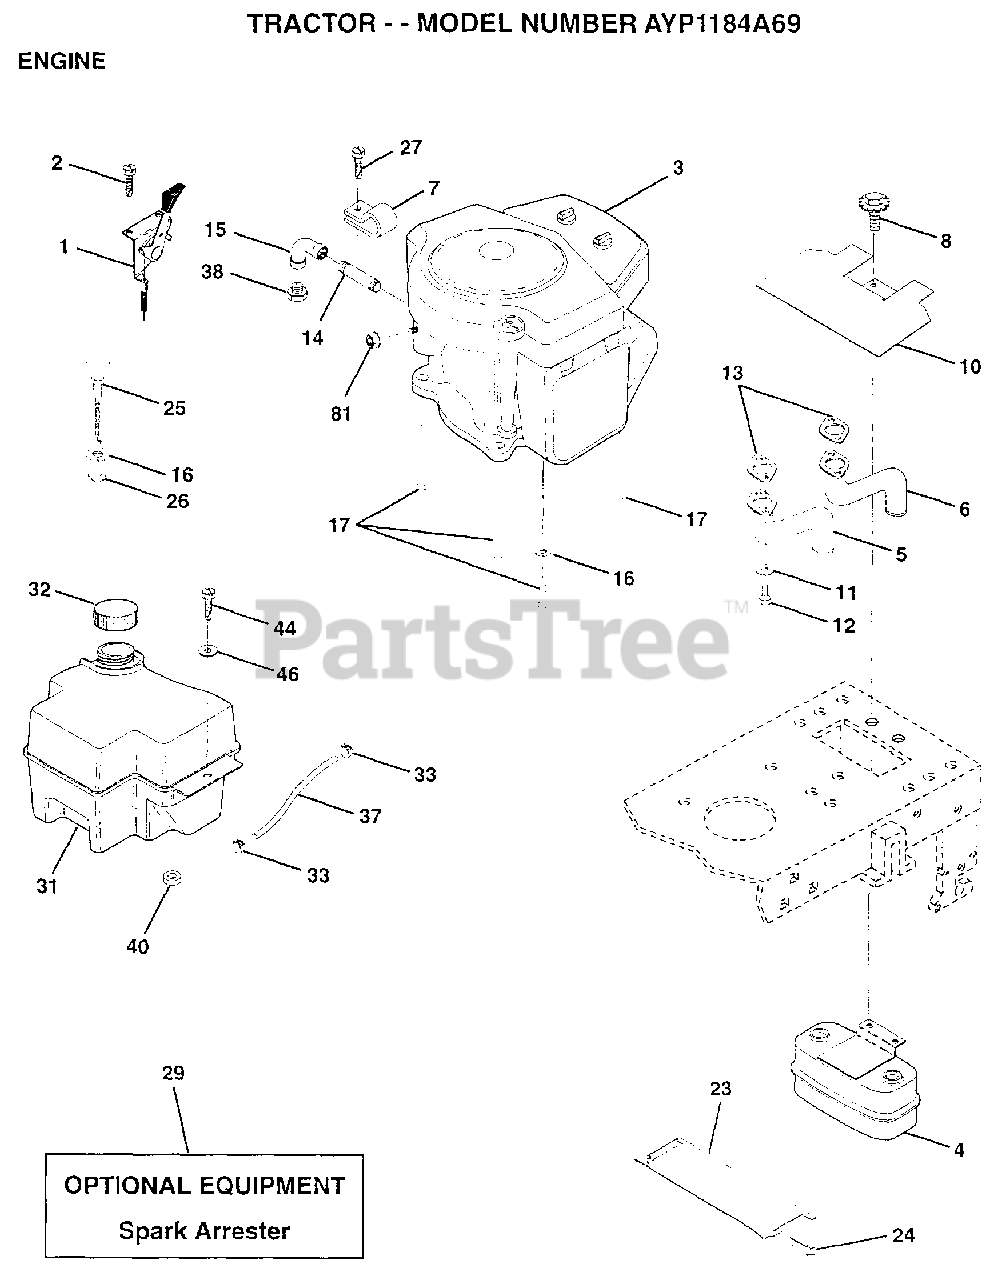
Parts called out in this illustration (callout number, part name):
1	CONTROL THRT 35.5
2	SCREW LT
4	MUFFLER.TW.LOTONE
5	EXHAUST.B&S.18.LH
6	EXHAUST.B&S.18.RH
7	CLAMP.TUBE.DBL.EN
8	BOLT.5/16-18.UNC
10	SHIELD.HEAT.
11	LOCKWASHER
13	GASKET MUFFLER
14	PIPE NIPPLE LT
15	ELBOW
16	LOCKWASHER
17	SCREW LT
24	SCREW
25	CONTROL.CHOKE.37
26	"NUT,KEPS 3/8-24IM"
27	SCREW.10-24X1/2
32	CAP ASM FUEL
33	HOSE CLAMP
37	LINE FUEL
44	SCREW HEX CRT
46	WASHER
81	NUT
